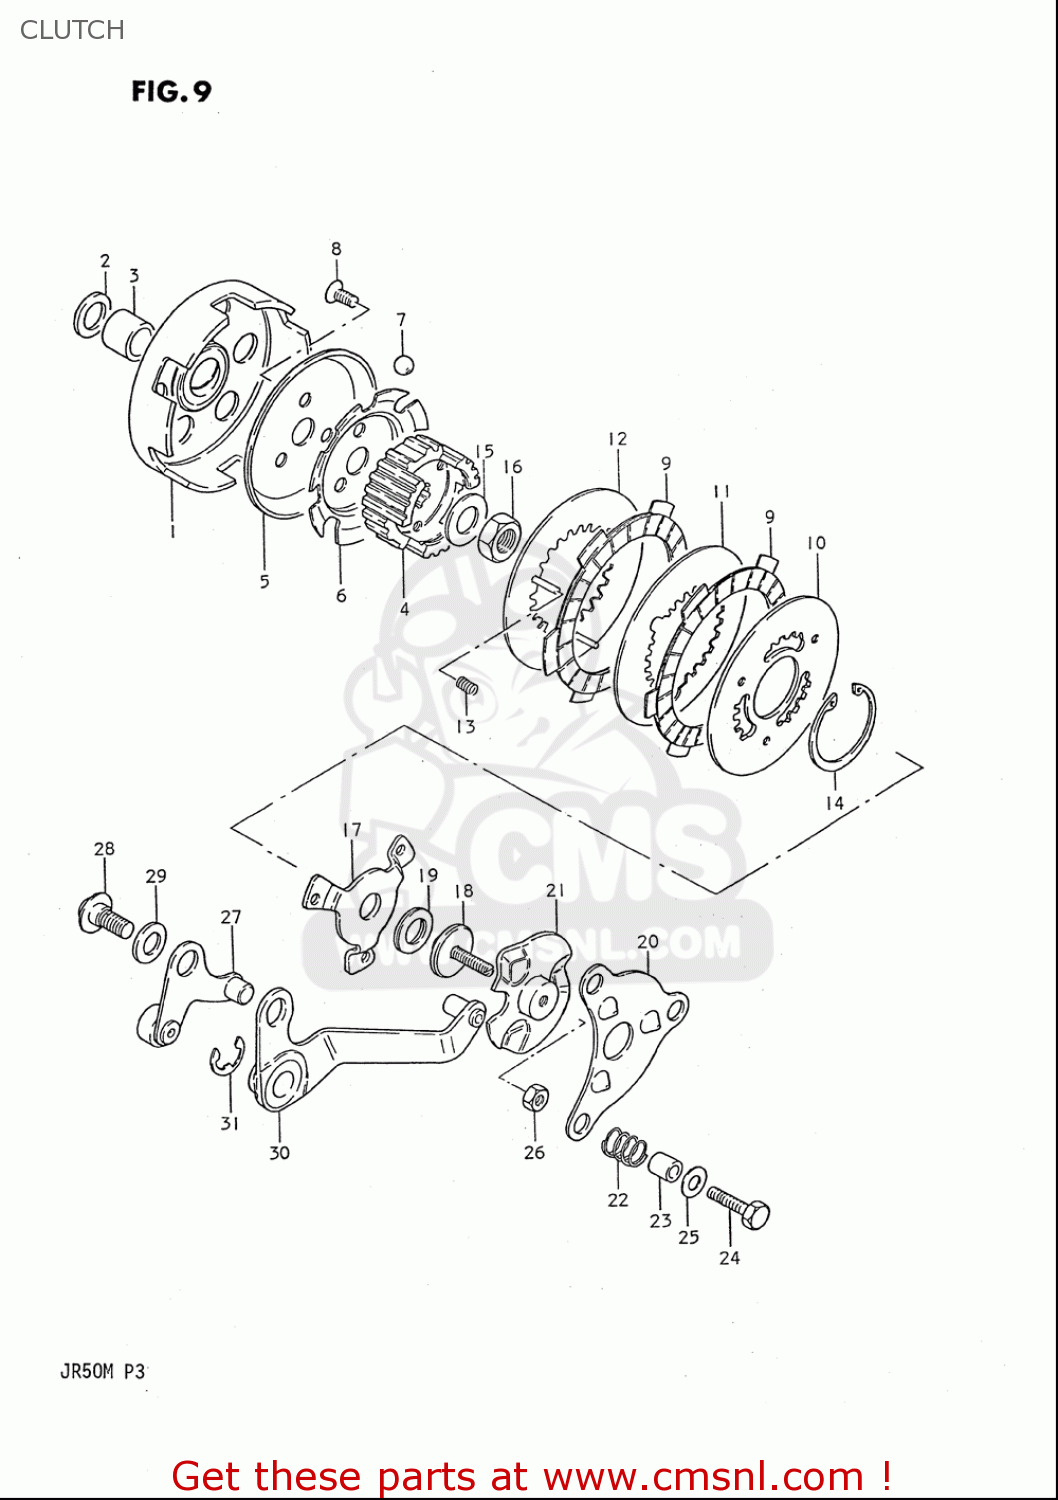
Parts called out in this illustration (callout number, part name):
1	GEAR,PRIMARY DRIVE
2	WASHER(14X23X3)
3	SPACER(14X19X18)
4	HUB,CLUTCH SLEEVE
5	PLATE,CLUTCH BALL
6	GUIDE,CLUTCH BALL
7	BALL
8	SCREW
9	PLATE,CLUTCH DRIVE (NAS)
10	PLATE,CLUTCH DRIVEN OUTER (NAS)
11	PLATE,CLUTCH DRIVEN (NAS)
12	PLATE,CLUTCH INNER
13	SPRING
14	CIRCLIP
15	WASHER
16	NUT
17	PLATE,CLUTCH PRESSURE
18	PIECE,CLUTCH PUSH
19	BEARING(10X22X2.8)
20	PLATE,CLUTCH RELEASE
21	PLATE,CLUTCH RELEASE,INNER
22	SPRING
23	SPACER(6X9X10.3)
24	BOLT
25	WASHER
26	NUT
27	PLATE,CLUTCH RELEASE ARM LINK
28	BOLT(8X17)
29	SHIM(8X16X1)
30	ARM,CLUTCH RELEASE PLATE
31	E RING
